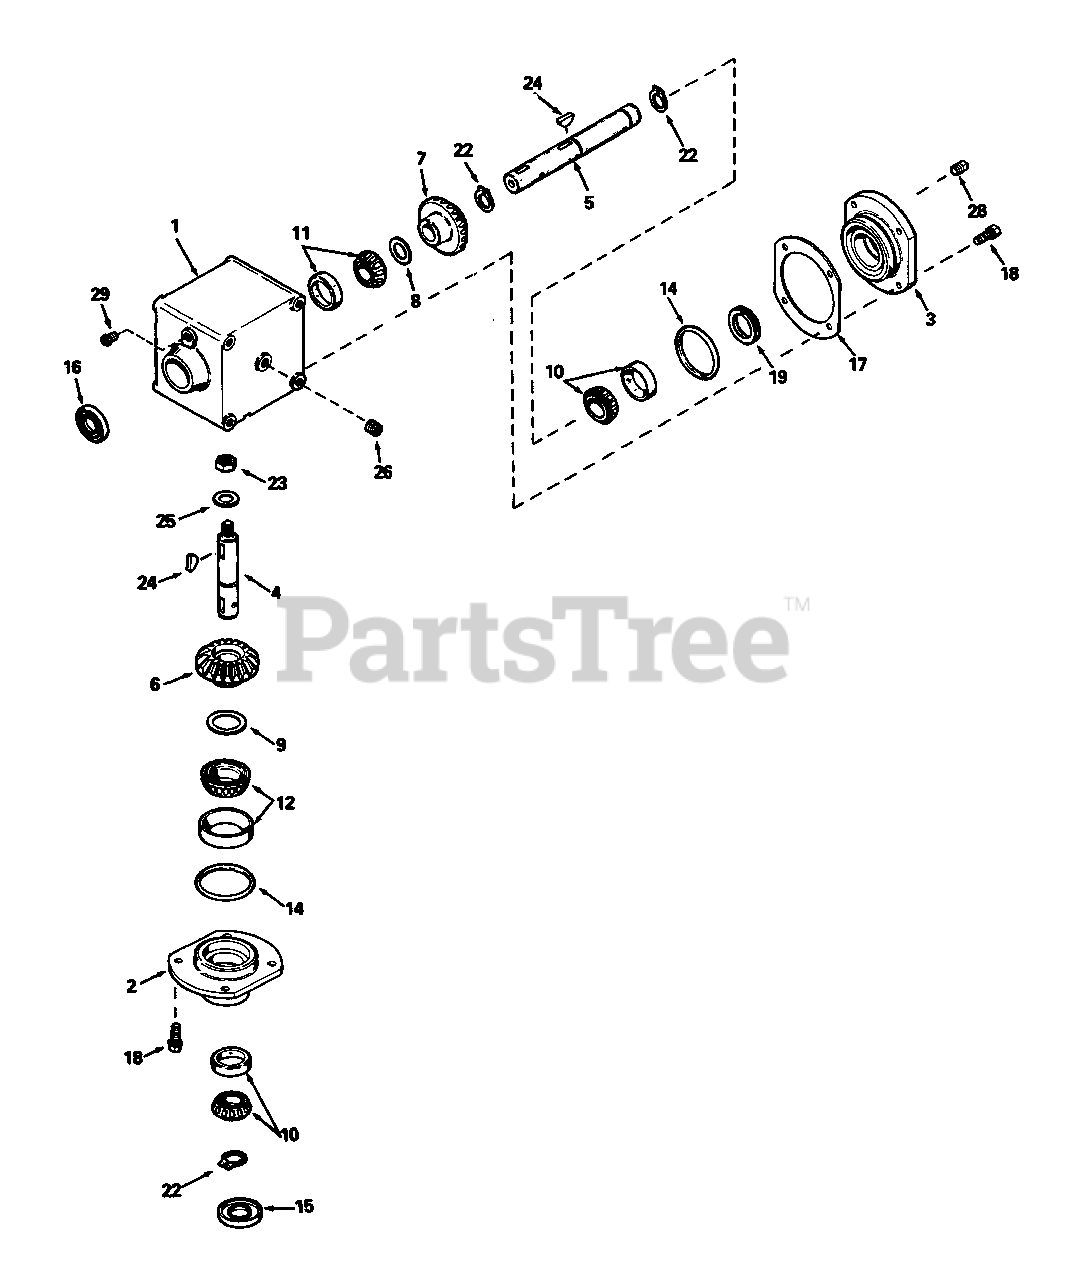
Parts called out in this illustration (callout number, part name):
1	HOUSING, Right Angle Drive
2	CAP, Retainer
3	CAP, Retainer
4	SHAFT, Input
5	SHAFT, Output
6	GEAR, Bevel
7	GEAR, Bevel
8	SHIM (1-1/2" OD x 1-1/64" ID x .002 Thick)
9	SHIM (2.000" OD x 1.531" ID x .002 Thick)
10	BEARING & CUP ASSY.
11	BEARING & CUP ASSY.
12	BEARING & CUP ASSY.
15	SEAL, Oil
16	SEAL, Oil
17	SHIM, Cap Retainer
18	SCREW, Hex Hd., Sems, 5/16-18 x 1
19	RING, Load
22	RING, Retaining
23	JAM NUT, 3/4-16
24	KEY, Woodruff
25	WASHER, Flat
26	PLUG, Pipe, 1/4-18
28	PLUG, Pipe
29	VALVE, Relief
